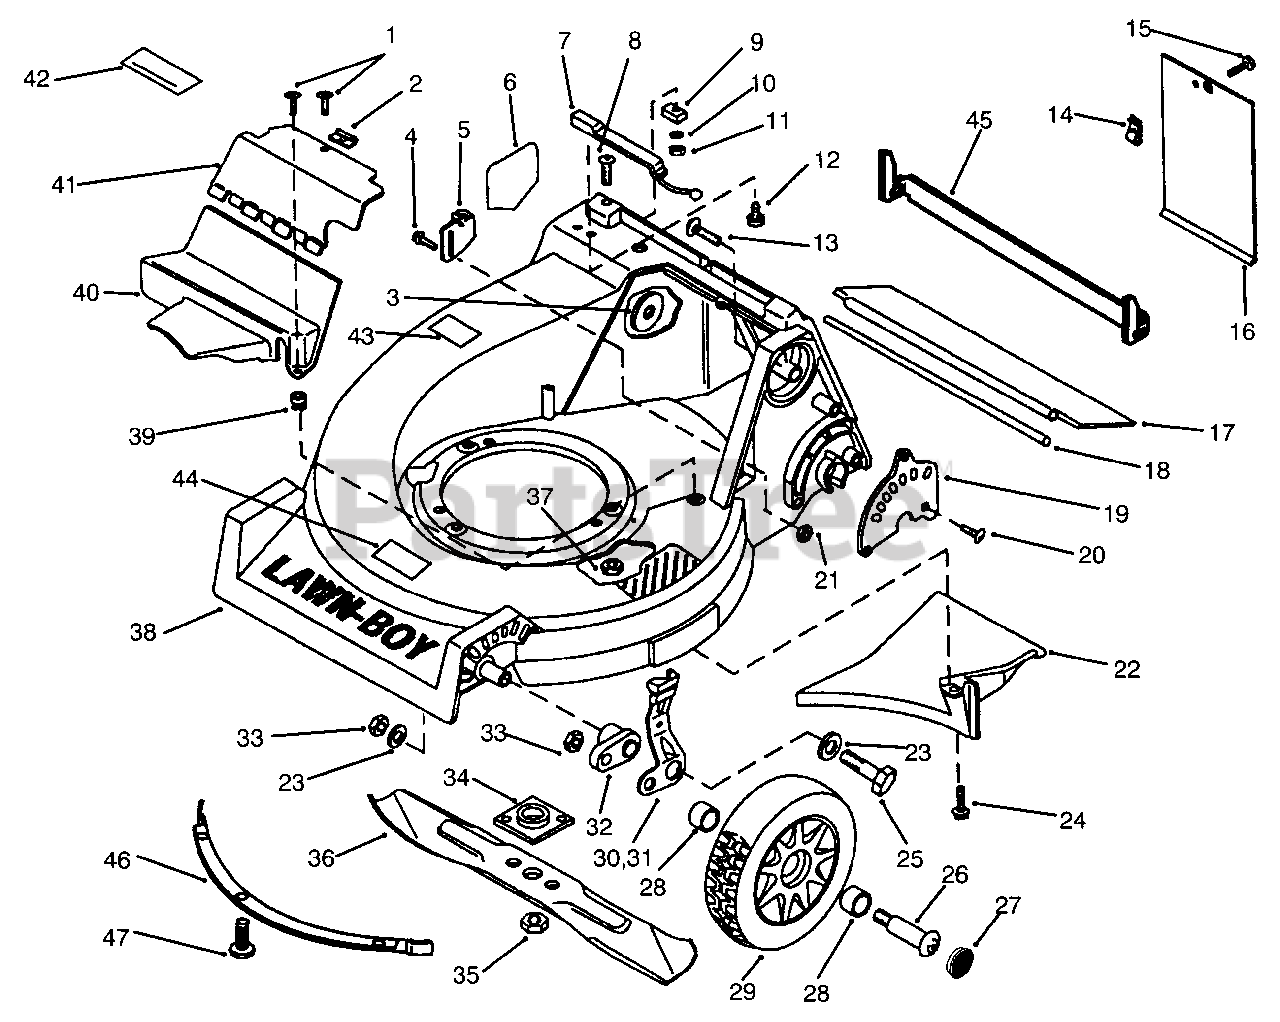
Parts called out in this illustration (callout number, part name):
2	Speednut
3	Washer-R.H. Handle
5	Anchor-Cable
6	Decal-Blade Warning
7	Switch-Bag Lock
9	Assembly-Magnet
10	Lockwasher
13	Bolt-Handle Mounting
14	Speednut
16	Door-Access
17	Shield-Trailing
18	Rod-Trailing Shield
19	Plate-Height Adjust
20	Screw-Plate to Housing
21	Nut-Cable Anchor/Hsg.
24	Screw-Baffle to Housing
26	Shoulder Bolt-Wheel
29	Assembly-Wheel & Tire (Incl. Ref. No. 28)
30	Assy.-Knob & Spring, L.H.
32	Arm-Front Height Adj.
34	Assembly-Collar & Plate
35	Nut-Blade
36	Blade-21"
37	Locknut-Mtg Plate/Hsg.
38	Assembly-Housing (Incl. Ref. No. 3, 6,13, 22 & 24)
39	Grommet
40	Cover-Lower Drive
41	Cover-Upper Drive (Incl. Ref. No. 42)
42	Decal-Warning
43	Decal-Sound Emission
44	Decal-Spark Plug
45	Housing-Shield
46	Baffle-Front
47	Screw-Baffle, Front
